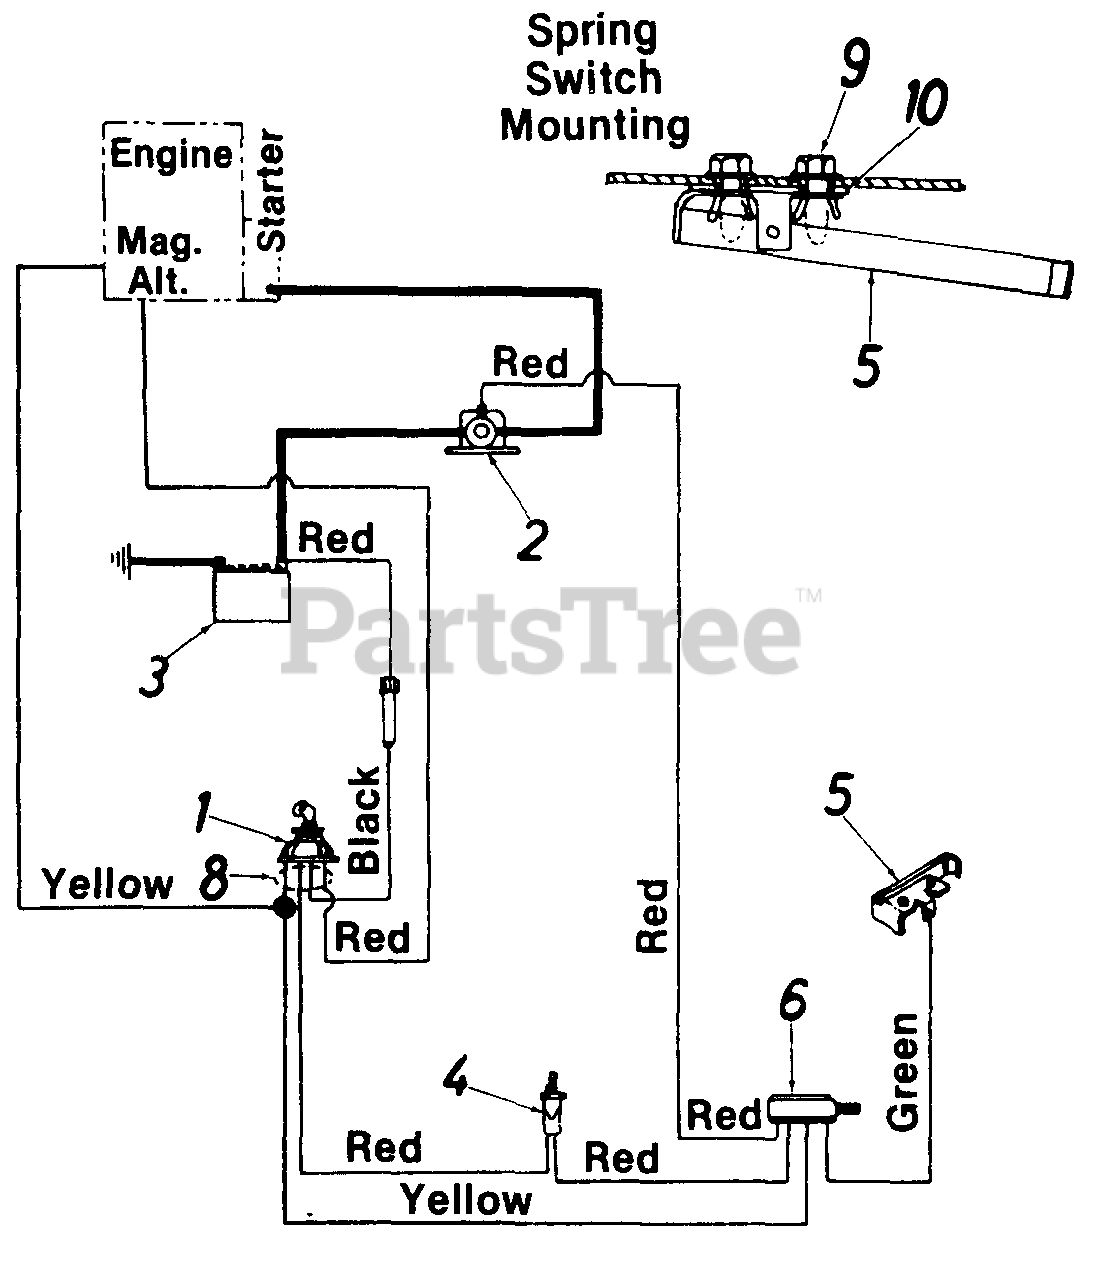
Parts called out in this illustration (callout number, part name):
1	Ignition Switch
2	Solenoid
4	Safety Switch (Clutch)
5	Spring Switch (Reverse)
6	Safety Switch (Lift)
8	Wire Harness
9	Hex Wash. Hd. Tap Scr. #8 x 1/2" Lg.
10	Insulator Nut Plate
